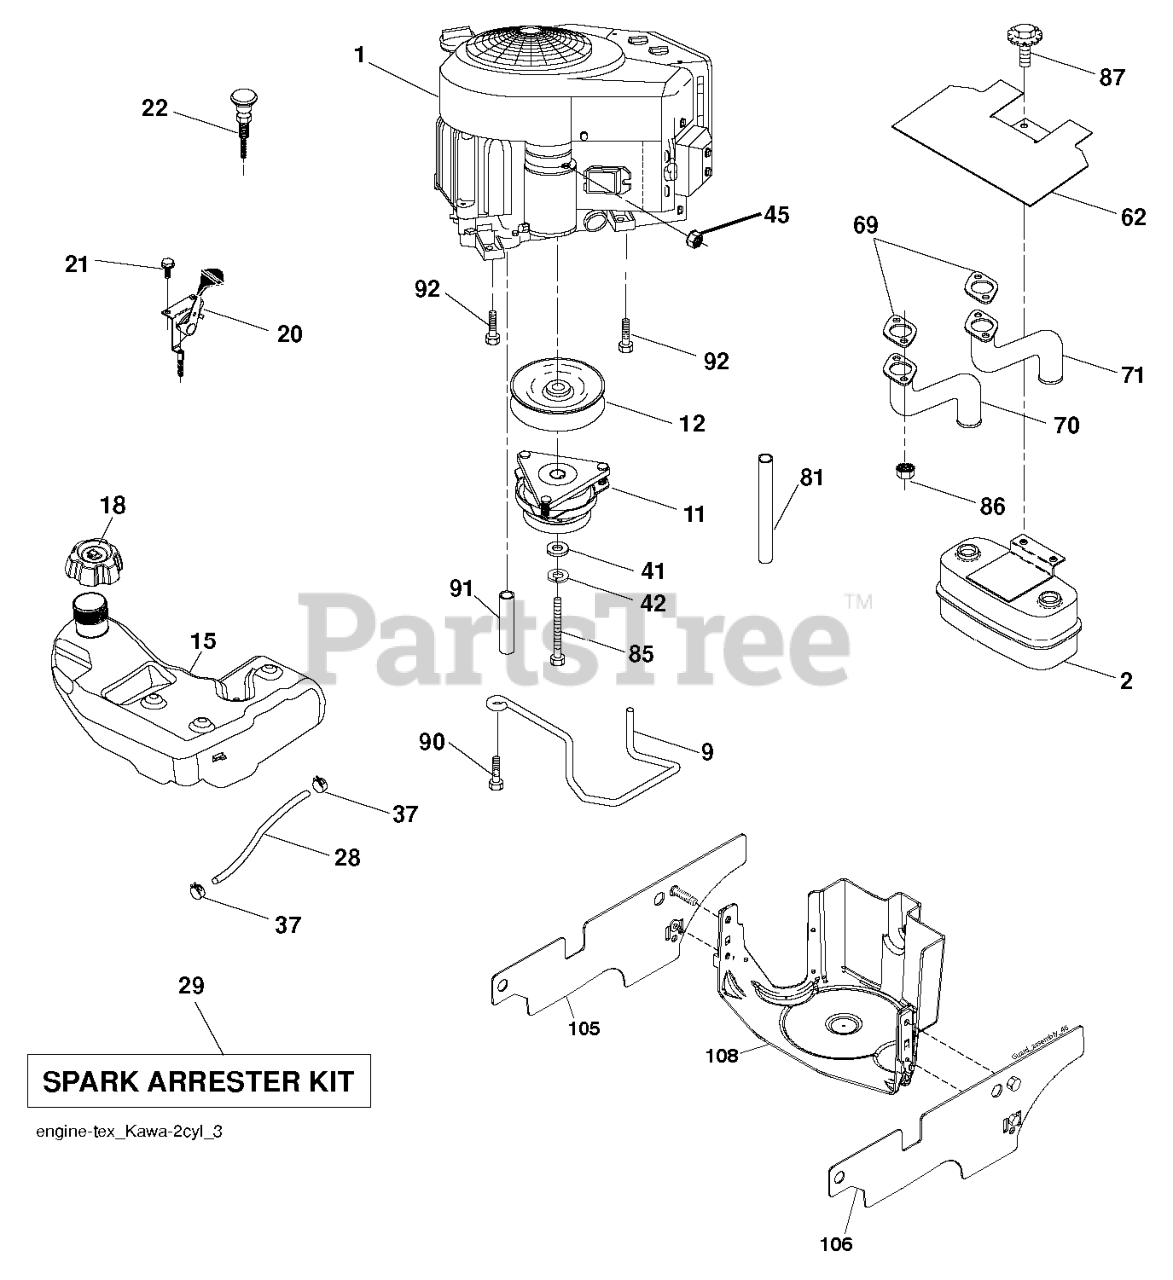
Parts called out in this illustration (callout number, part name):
2	MUFFLER.TWIN.CYL.LOW.TONE
9	KEEPER.BELT.ENGINE.4.2
11	RB.CLUTCH.OGURA.4.4.PD
12	PULLEY.ENGINE.TUFFTORQ
15	TANK.FUEL.4GAL
18	RP CAP FUEL
20	THROTTLE CABLE
21	SCREW.#10 X 0.750.BOS
22	CONTROL.CHOKE.ERGO.PUSH-IN.BLA
28	REPL BY 532 00 85-43
29	KIT.SPARK ARRESTOR 794945 B&S
37	HOSE CLAMP
42	LOCKWASHER
45	NUT
62	RP SHIELD HEAT MUFFLER
69	GASKET.EXHAUST.KAWASAKI.15-1
70	EXHAUST TUBE LH KAWI
71	EXHAUST TUBE RH KAWI
81	TUBE, DRAIN OIL ASM.
85	BOLT HEX 7/16-20X4-1/4"
86	NUT.HEX.FLANGE.TOPLOCK
87	BOLT.5/16-18UNCX3/4 W/SEMS.BLK
90	SCREW 3/8-16X1
91	BUSHING.1.375OD
92	SCREW 3/8-16X1
108	ENGINE COVER
